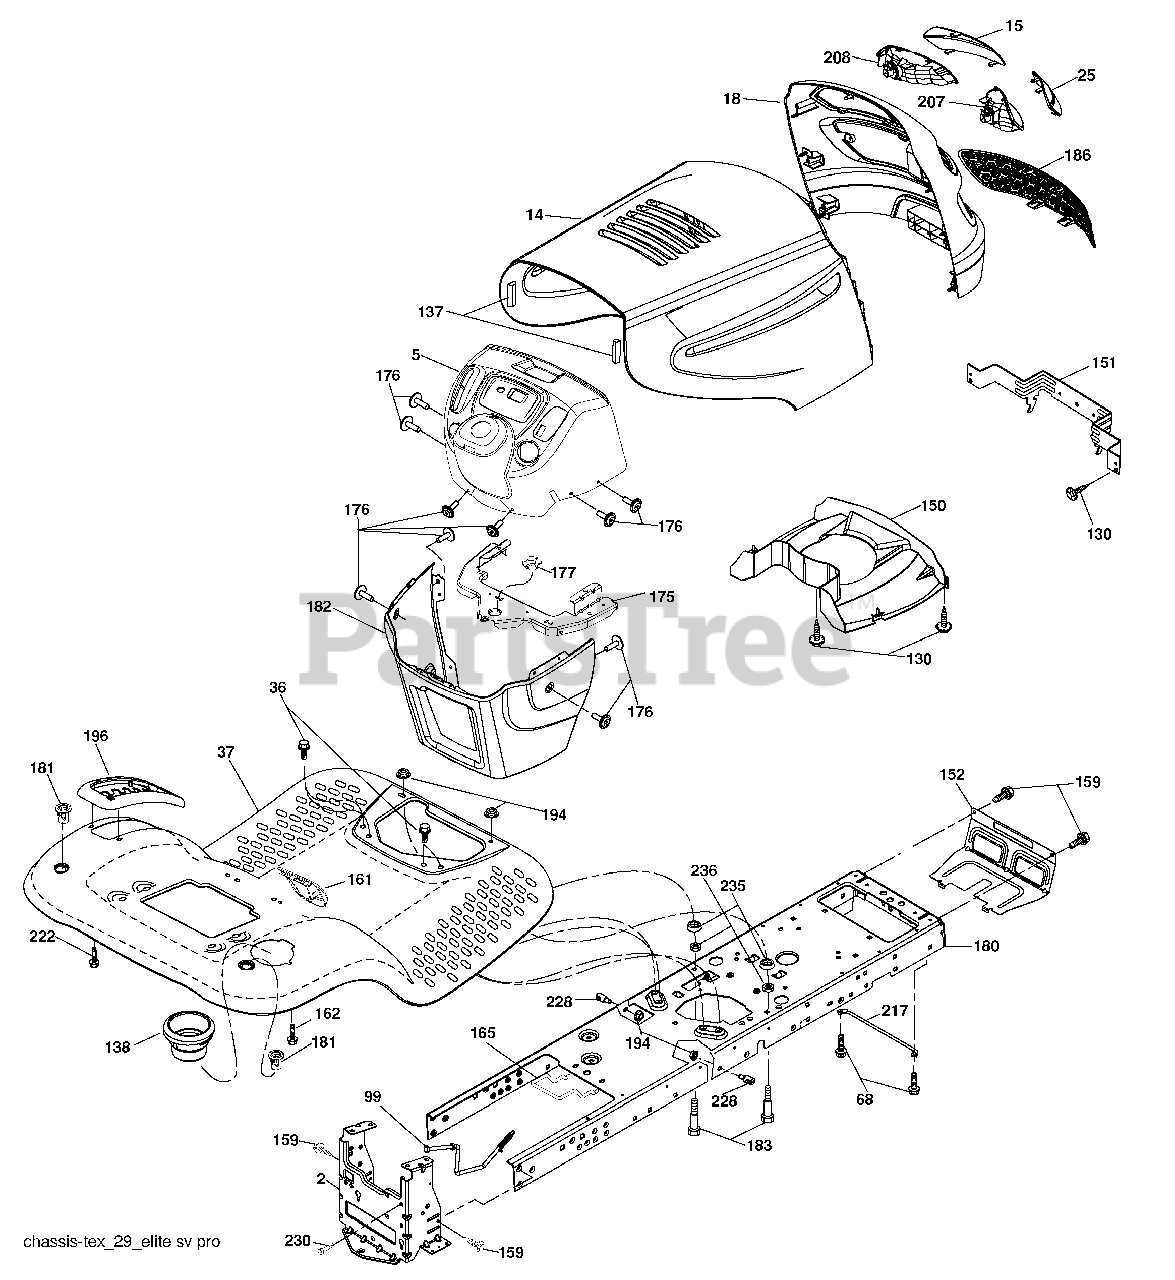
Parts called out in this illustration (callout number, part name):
2	Drawbar
5	Dash
14	Hood
15	Lens Grille LH
18	Grille
25	Lens Grille RH
36	Screw 5/16-18 x 3/4
37	Fender
68	Screw THDROL 5/16-18 x 1/2
99	Rod Bypass Asm
130	Screw 10 x 3/4 Single Lead-Hex
137	Bumper Hood
138	Cupholder
150	Duct Heat Hood
151	Bracket Pivot
152	Shield Browning/Debris
159	Screw Hexwsh Thdrol 3/8-16 x 3/4
161	Window Fuel
162	Screw Hex Wsh Hi-Lo 1/4 x 1/2 unc
165	Support Tank Rear
175	Crossmember
176	Screw 10-24 x 5/8 Wshd Qdrx
177	Bushing Steering
181	Bushing Mtg. Fender Crgo.
182	Dash Lower
183	Bolt Fin Hex 5/16-18 x 1-1/4
189	Screw 5/16-18 x 3/4
194	Nut Lock Hex Flange 5/16-18
196	Console Asm. Deck Lift
207	Bezel RH
208	Bezel LH
217	Rod Pivot Chassis
222	Screw thd Roll 1/4-20 x 5/8
228	Stud Fastener
230	Bolt Shoulder 5/16-18
235	Spacer Fender
236	Nut Center Lock 5/16-18 unc
